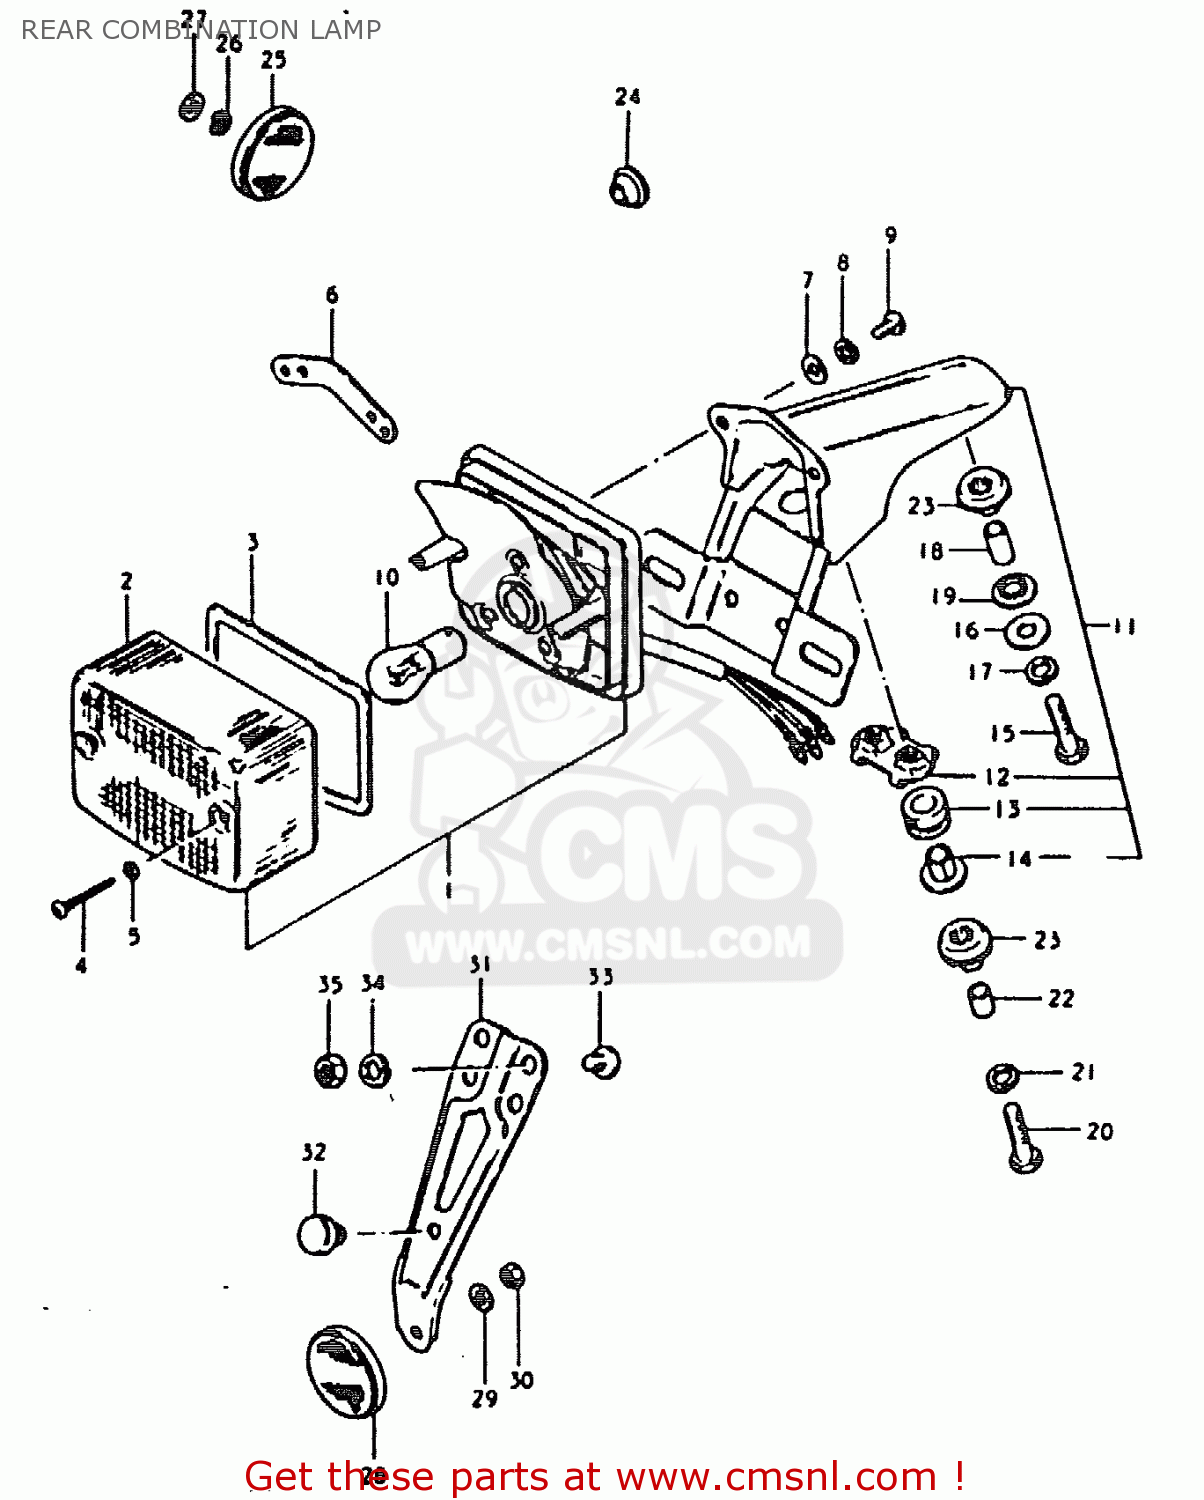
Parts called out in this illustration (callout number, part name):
1	LAMP UNIT,REAR COMBINATION
2	LENS
3	GASKET (NAS)
4	BOLT
5	GASKET (NAS)
6	PLATE,REAR COMBINATION LAMP
7	WASHER,5MM
8	WASHER,LOCK
9	SCREW
10	BULB(6V32/3CP,STANLEY)
11	BRACKET UNIT,TAIL LAMP
12	PLATE
13	CUSHION
14	SPACER
15	BOLT
16	WASHER (6.5X20X1.2)
17	LOCK WASHER
18	SPACER
19	CUSHION
20	BOLT 6X40
21	LOCK WASHER
22	SPACER (6.8X10X11.5)
23	CUSHION
24	GROMMET
25	REFLEX REFLECTOR,FR
26	LOCK WASHER
27	WASHER
28	REFLEX REFLECTOR,RR
29	WASHER
30	NUT
31	BRACKET
32	CUSHION
33	SCREW
34	LOCK WASHER
35	NUT 6MM
